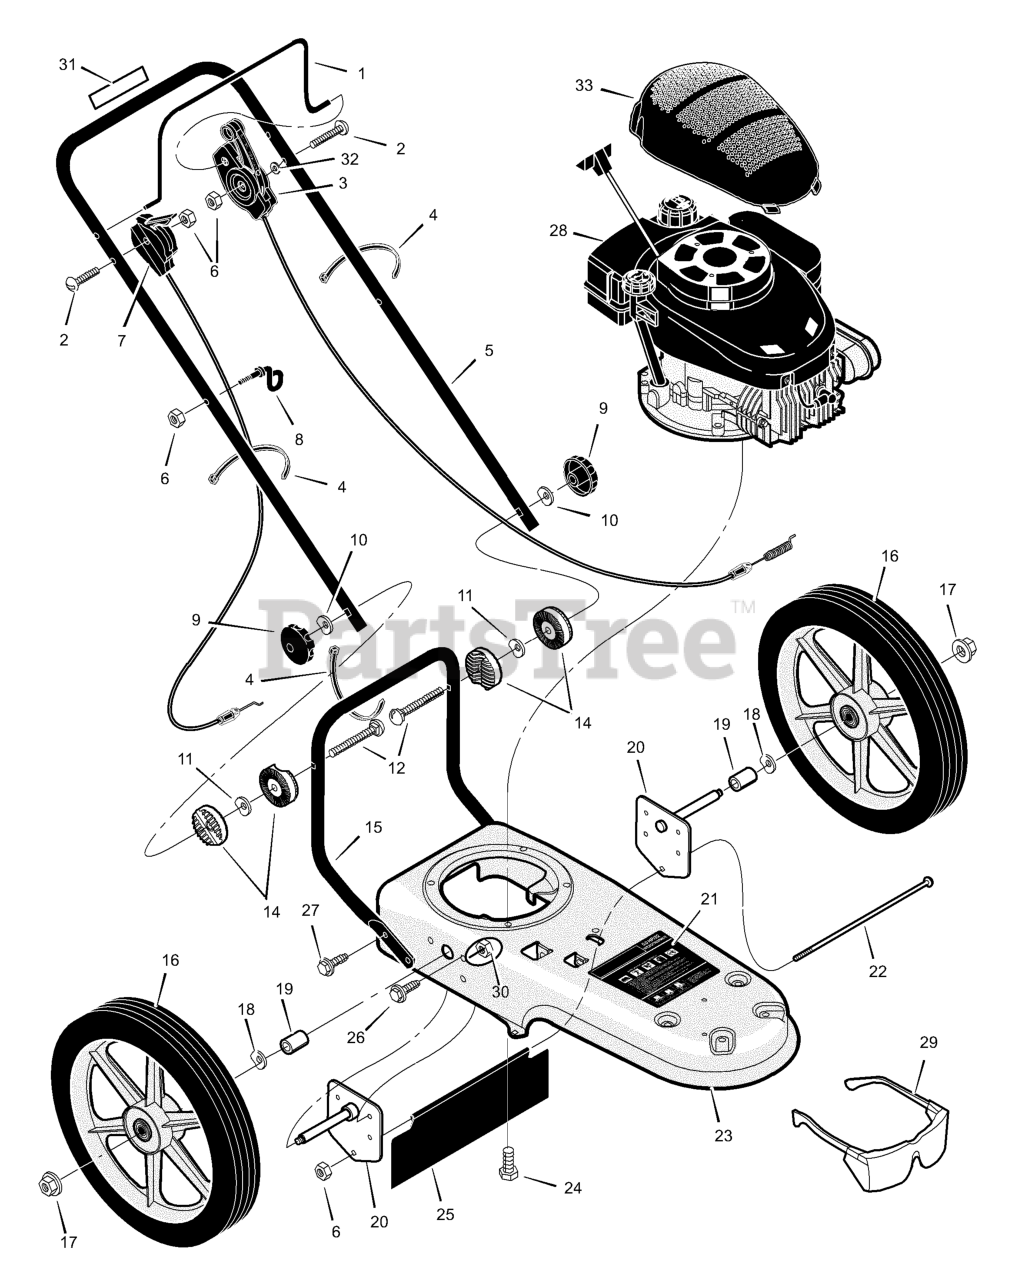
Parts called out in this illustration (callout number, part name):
1	Lever, Stop
3	Cable, Control Latching
4	Tie, Cable
5	Handle
6	Nut
7	Control, Throttle
8	Guide, Rope
9	Knob, Handle
11	Washer, Spring
14	Pivot, Handle
15	Handle, Lower
16	Wheel & Tire
17	Nut, Axle
18	Washer, Spring
20	Assembly, Axle & Bracket
21	Decal
22	Bolt, Carriage
23	Frame, Trimmer
25	Shield, Trailing
26	Bolt
28	Engine *
29	Protection, Eye
30	Nut
33	Shroud, Engine
